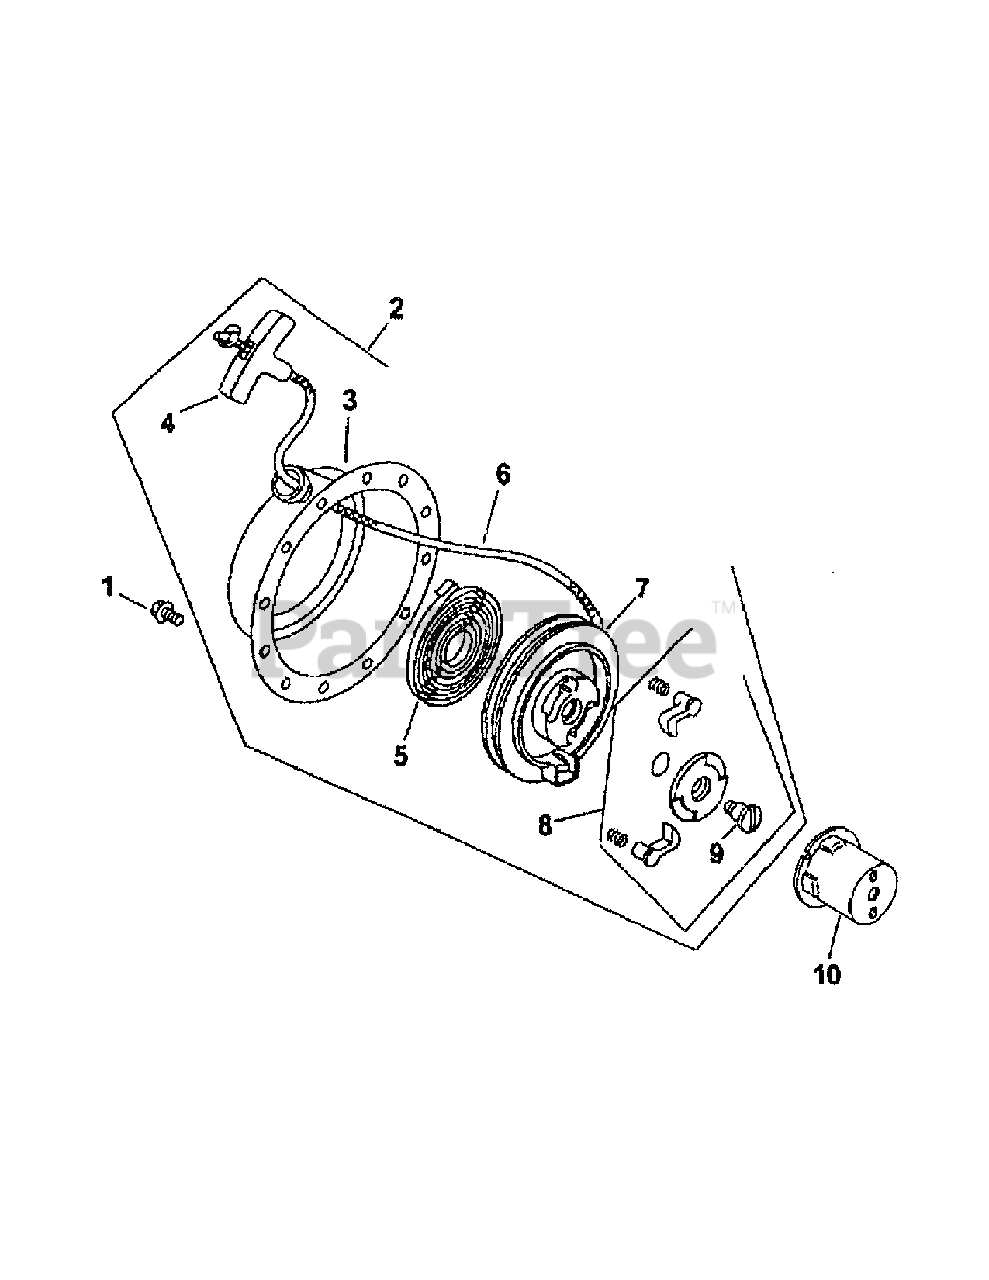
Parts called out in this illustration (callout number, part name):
2	Starter, Retractable
3	Housing Assembly
4	Handle, Starter
5	Spring, Recoil
6	Rope, Starter
7	Pulley
8	Kit, Pawl Repair
10	Cup, Starter Drive
